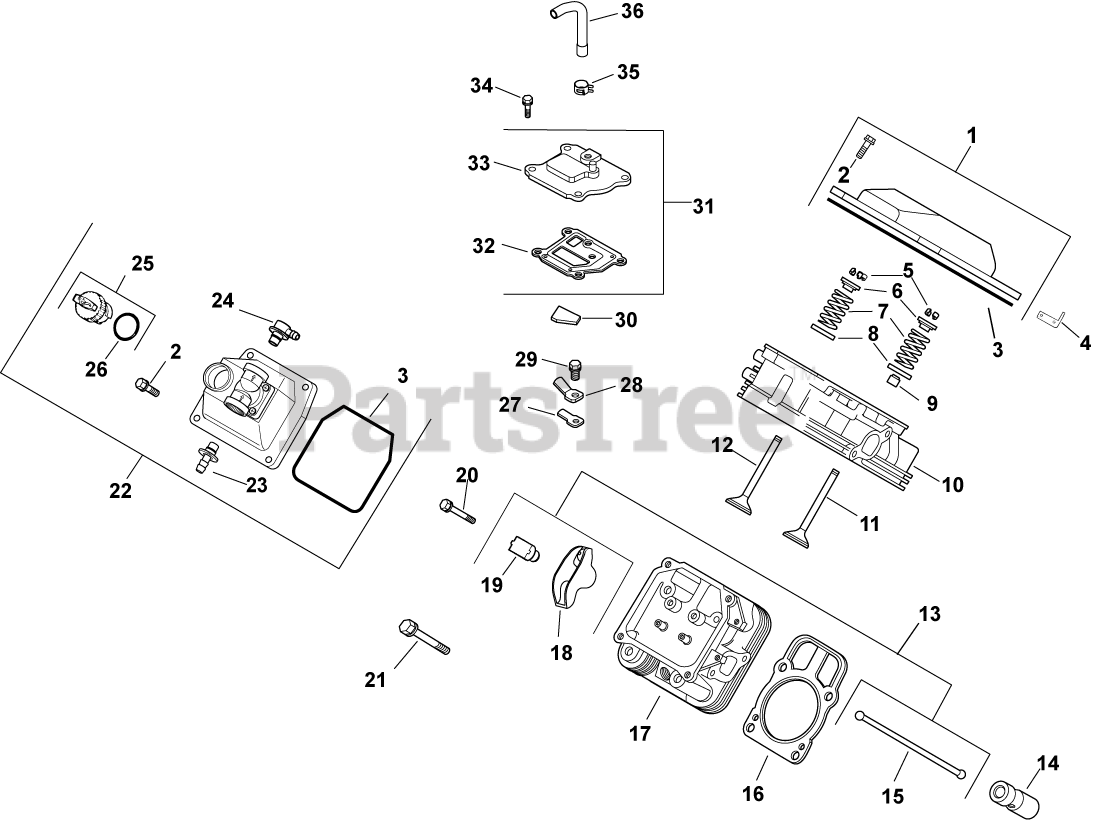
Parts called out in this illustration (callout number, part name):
1	KIT, VALVE COVER-PLAIN
2	SCREW, FLG M6X1.0X30
3	O-RING (YELLOW), VALVE COVER
4	STRAP, LIFTING-USE 25 445 03-S
5	KIT, RETAINER
6	RETAINER, VALVE SPRING - USE 25 173 28-S
7	SPRING, VALVE
8	RETAINER, SPRING
9	SEAL, VALVE STEM - (#2503214S)
10	HEAD, ASSEM CYLINDER #1 -USE 24 318 107-
11	VALVE, INTAKE (STD)
12	VALVE, EXHAUST (STD) - USE 32 016 01-S
13	KIT, VALVE TRAIN
14	LIFTER, HYDRAULIC VALVE-USE 25 351 10-S
15	ROD, PUSH
16	KIT, CYL HEAD GASKET (C17-22)
17	HEAD, ASSEM CYLINDER #2 -USE 24 318 115-
18	ARM, ROCKER
19	PIVOT, ROCKER ARM
20	SCREW, FLG M6X1.0X34
21	SCREW - USE 62 086 08-S
22	KIT, VALVE COVER-FUEL PUMP
23	KIT, STRAIGHT FITTING
24	KIT, 90 DEG. FITTING
25	CAP ASSY, OIL FILL (YELLOW)
26	O-RING-USE 24 153 32-S
27	REED, BREATHER
28	RETAINER, REED
29	SCREW, FLG THD FRM M5X.8X10
30	FILTER, BREATHER
31	KIT, BREATHER ASSEMBLY
32	GASKET, BREATHER-USE 24 041 67-S
33	COVER, BREATHER -USE 24 033 01-S
34	SCREW,FLG THD FRM M6X1.0X20-(#25086396S)
35	CLAMP, HOSE (KM)-USE 25 237 31-S
36	HOSE, BREATHER
2401602-S	VALVE, EXHAUST (.25)
2401702-S	VALVE, INTAKE (.25)
